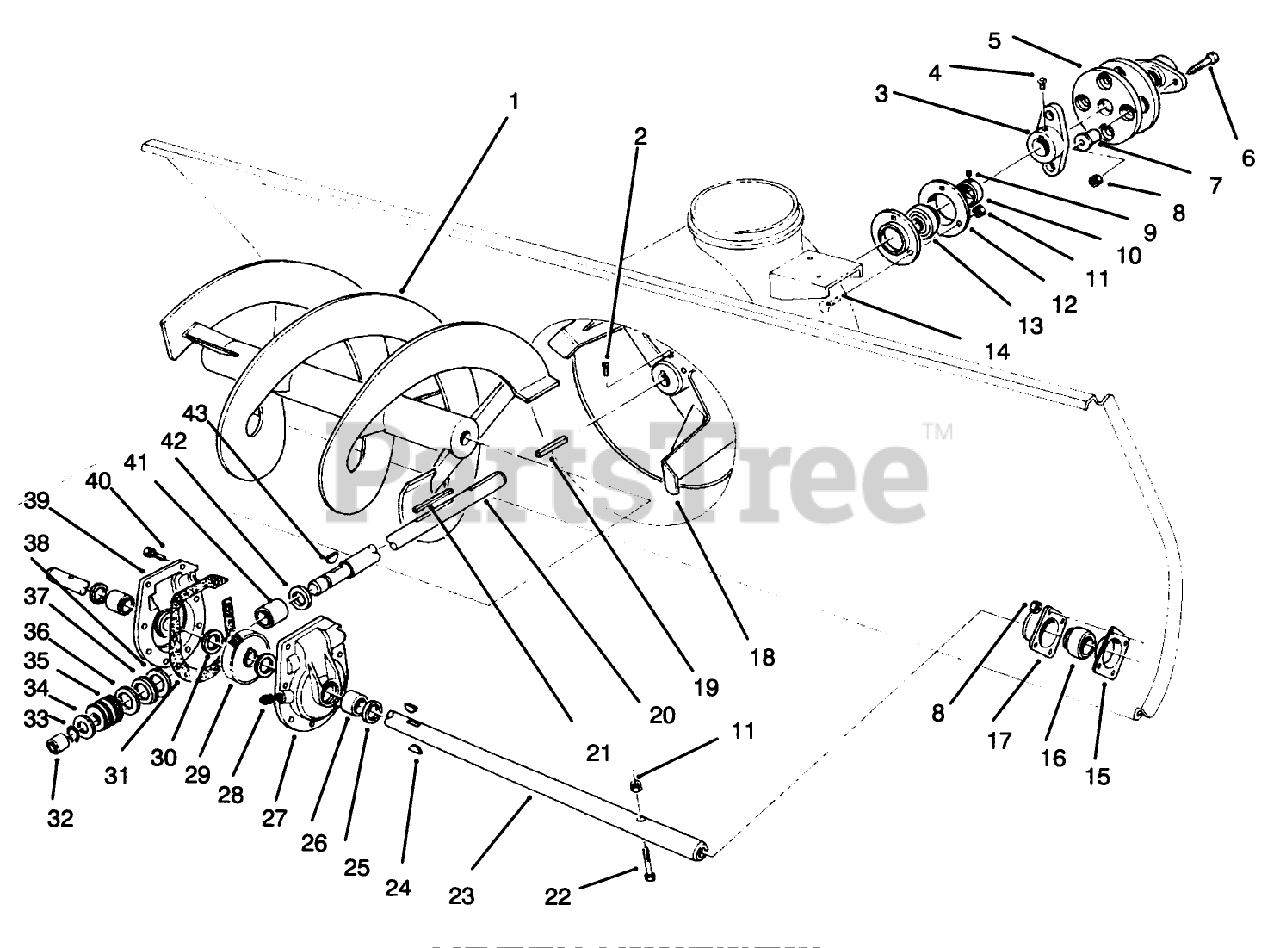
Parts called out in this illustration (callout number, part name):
1	Auger RH
2	SCREW-SET, SQH
3	HUB WA (KEY) R
4	SCREW-SET
5	COUPLING-RUBBER
6	SCREW-HH
7	SPACER-COUPLING, RUBBER
8	NUT-LOCK, NI
9	SCREW-HSH
10	EXT LOCKING COLLAR
11	NUT-LOCK, NI
12	BRG FLANGE
13	BALL BRG W/COLLAR
14	BOLT-CARR
15	BEARING-FLANGE, REAR
16	BEARING
17	BEARING-FLANGE, FRONT
18	IMPELLER ASM
19	KEY-SQUARE
20	IMPELLER SHAFT
22	SCREW-HH
23	SHAFT-AUGER
24	KEY-WOODRUFF
25	SEAL-OIL
26	BUSHING
27	Gear Case & Bushing Assy., (Incl. Ref. #25 & 26)
28	PLUG-PIPE, SQH
29	GEAR-WORM, 27T
30	WASHER-THRUST
31	GASKET-CASE, GEAR
32	BUSHING
33	Ring-Snap
34	WASHER-THRUST
36	THRUST-WASHER
37	BEARING-THRUST
38	WASHER-THRUST
39	Gear Case & Bushing Assy. (Incl. Ref. #25 & 26)
40	SCREW-TAPTITE
41	BUSHING-SPECIAL
42	RING-QUAD
43	KEY-WOODRUFF
